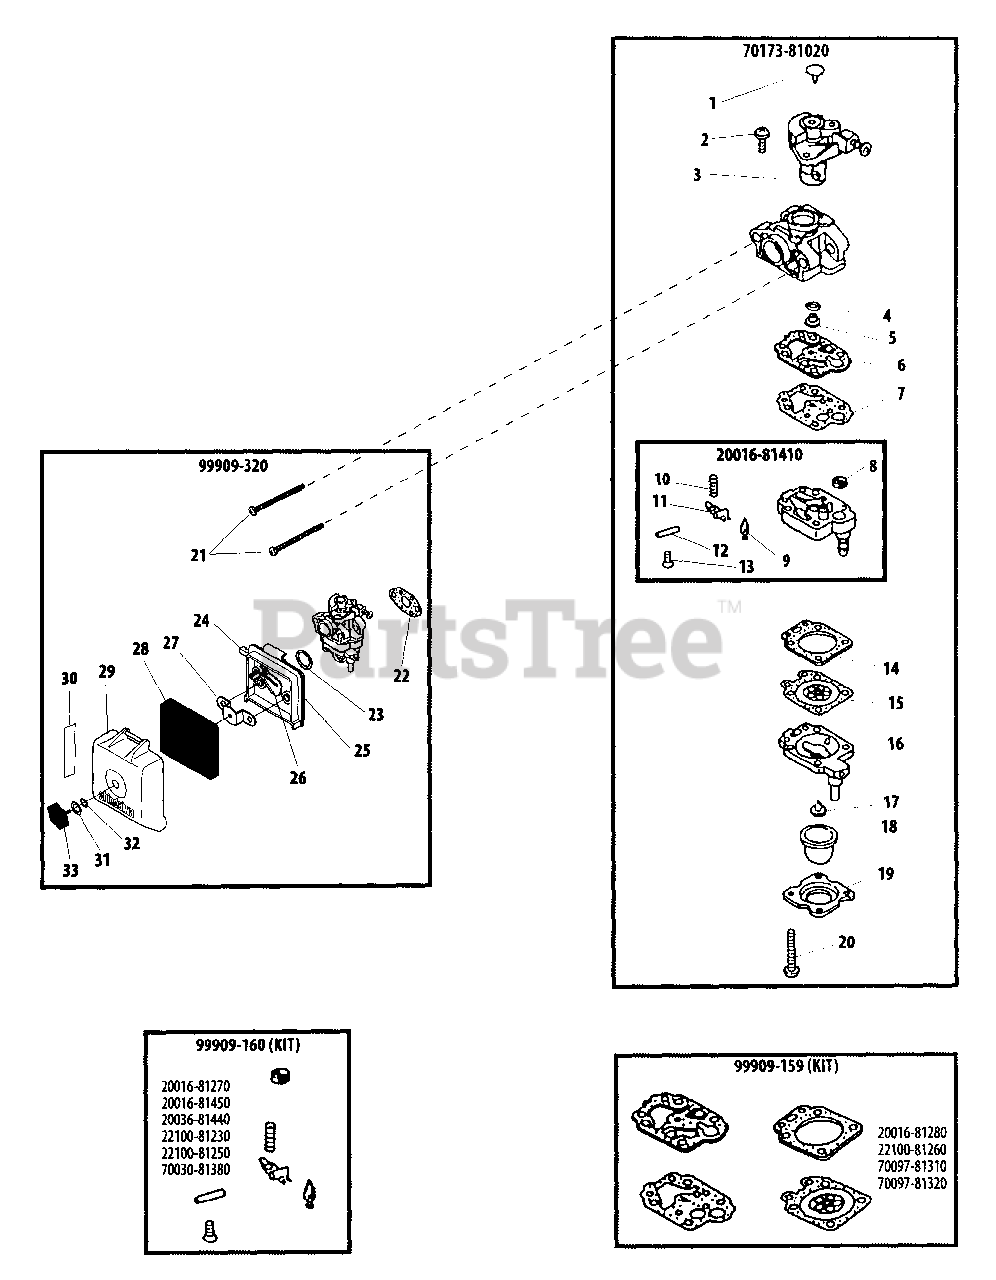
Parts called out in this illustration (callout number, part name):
1	PLUG, WELCH
2	SCREW
3	THROTTLE VALVE ASSY
4	O-RING
5	JET, MAIN - 38
6	GASKET, PUMP
7	DIAPHRAGM, PUMP
8	STRAINER
9	VALVE, INLET NEEDLE
10	SPRING, METERING LEVER
11	LEVER, METERING
12	PIN, METERING LEVER
13	SCREW, METERING LEVER PIN
14	GASKET, METERING
15	DIAPHRAGM, METERING
16	BASE, PURGE
17	VALVE, CHECK
18	BULB, PURGE
19	RETAINER, PURGE BULB
20	SCREW, PUMP COVER
21	SCREW - 5X67
22	GASKET
23	O-RING - 15
24	LEVER, CHOKE
25	CASE, AIR FILTER
26	PLATE, CHOKE
27	PLATE, PREVENT
28	FILTER, AIR - FOAM
29	COVER, AIR FILTER
30	LABEL - CHOKE
31	WASHER - CONICAL
32	O-RING
33	THUMBSCREW
20016-81410	PUMP BODY ASSY
70173-81020	CARBURETOR
99909-159	DIAPHRAGM/GASKET KIT
99909-160	REPAIR KIT
99909-320	AIR FILTER ASSY
